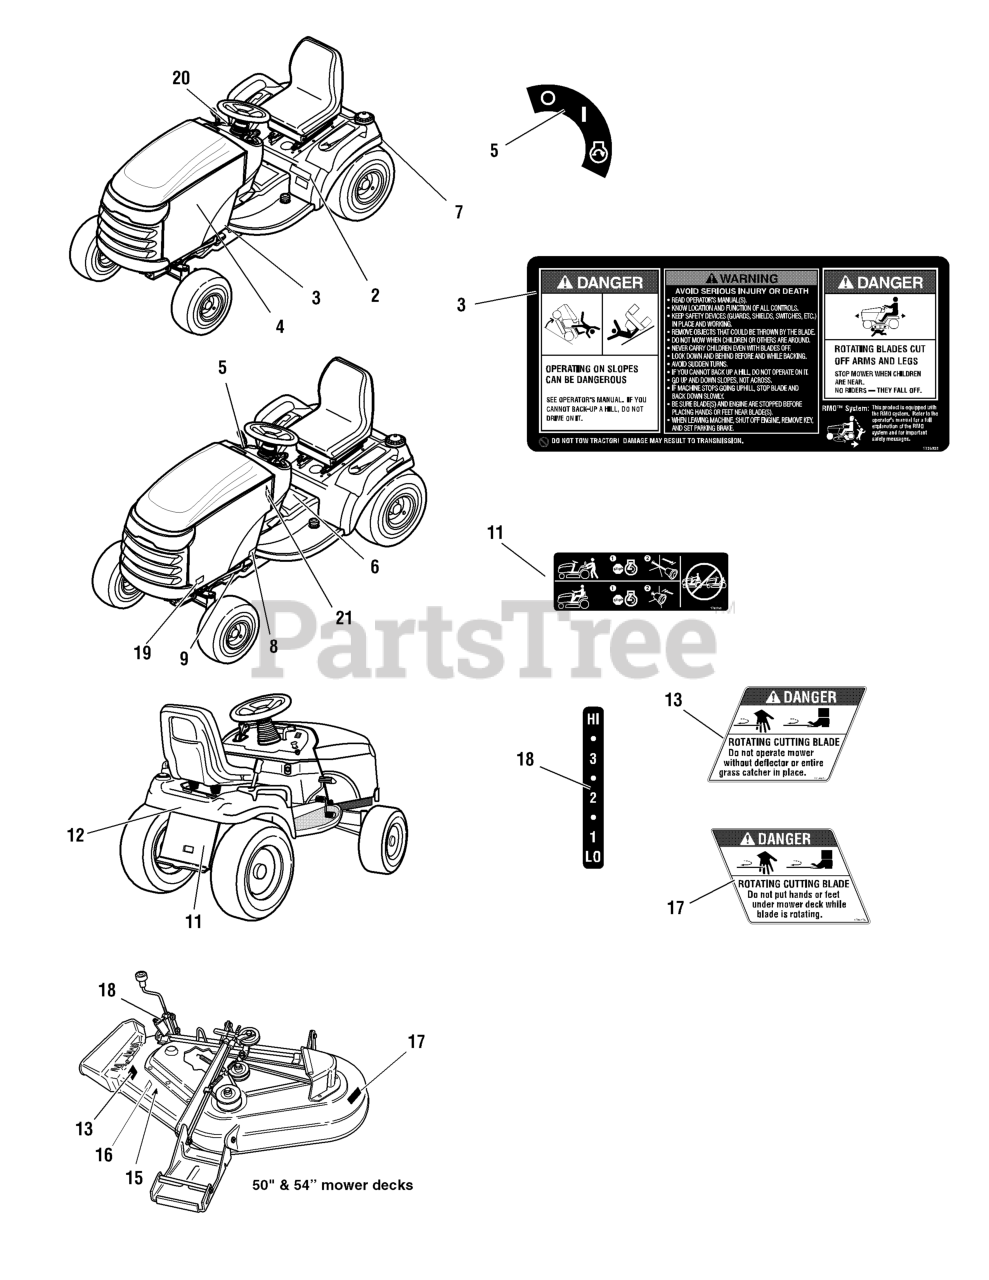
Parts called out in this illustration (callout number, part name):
2	DECAL, Differential Lock
3	DECAL, 30HP
4	DECAL, Hood Stripe
5	DECAL, Ignition Switch Symbols
6	DECAL, Tunnel Cover Danger Slopes, Blades
7	DECAL, Controlled Traction, Automatic
8	STICKER, Protection
9	DECAL, I.D. Plate
11	DECAL, Transmission Release Valve
12	DECAL, Craftsman, Rear Stripe
13	DECAL, Danger Do Not Operate w/o Deflector
15	DECAL, OPEI Certified
16	DECAL, 54" Cutting Width
17	DECAL, Danger Do Not Put Hand/Feet In Mower
18	DECAL, 1 2 3 4 5 6, Height of Cut White/Black
19	DECAL, PGT9500
20	DECAL, Power Steering
21	DECAL, Belt, Blade & Paint
